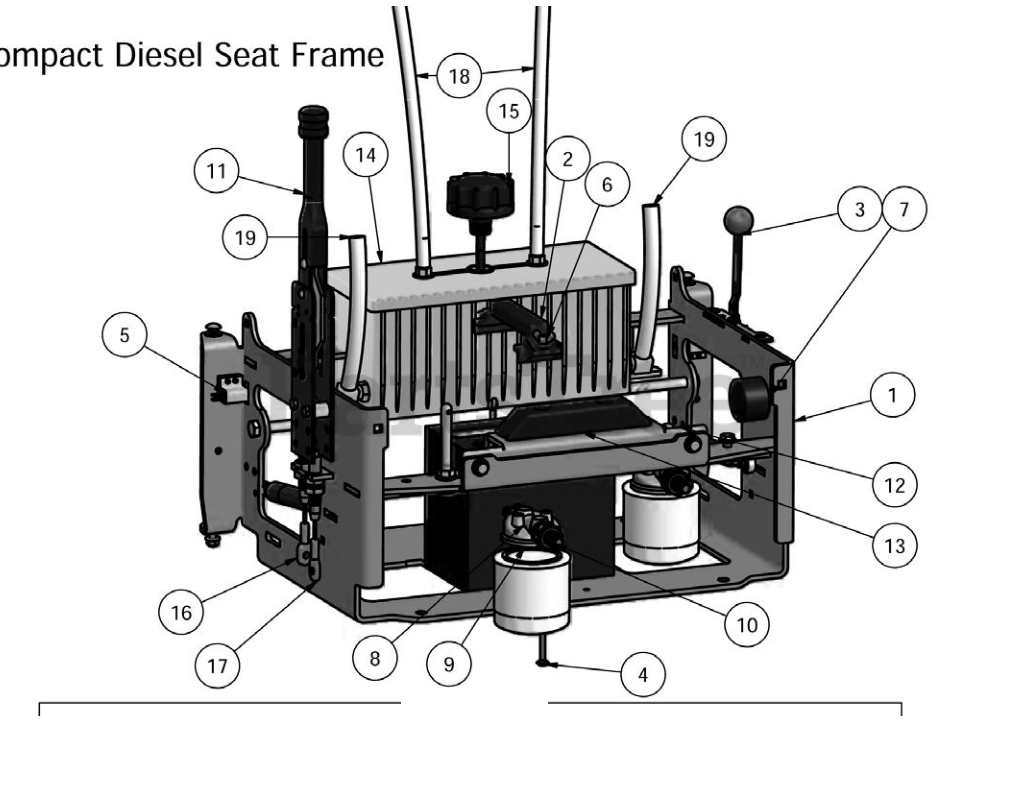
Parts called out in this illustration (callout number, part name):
1	Seat Frame
2	Battery Hold Down
3	Throttle Lever Assembly
4	9" Stove Bolt
5	Safety Switch
6	1/4" Wing Nut
8	Filter Head
9	Hydraulic Filter
10	Filter Head Fitting
11	Hand Brake Assembly
12	Compact Diesel Seat Bumper Bracket
13	8" Rubber Bumper
14	Aluminum Hydraulic Tank
15	Hydraulic Tank Cap
16	Short Brake Cable
17	Long Brake Cable
18	3/8" x 32" Clear Hose
19	1/2" x 9 1/4" Braided Hose
